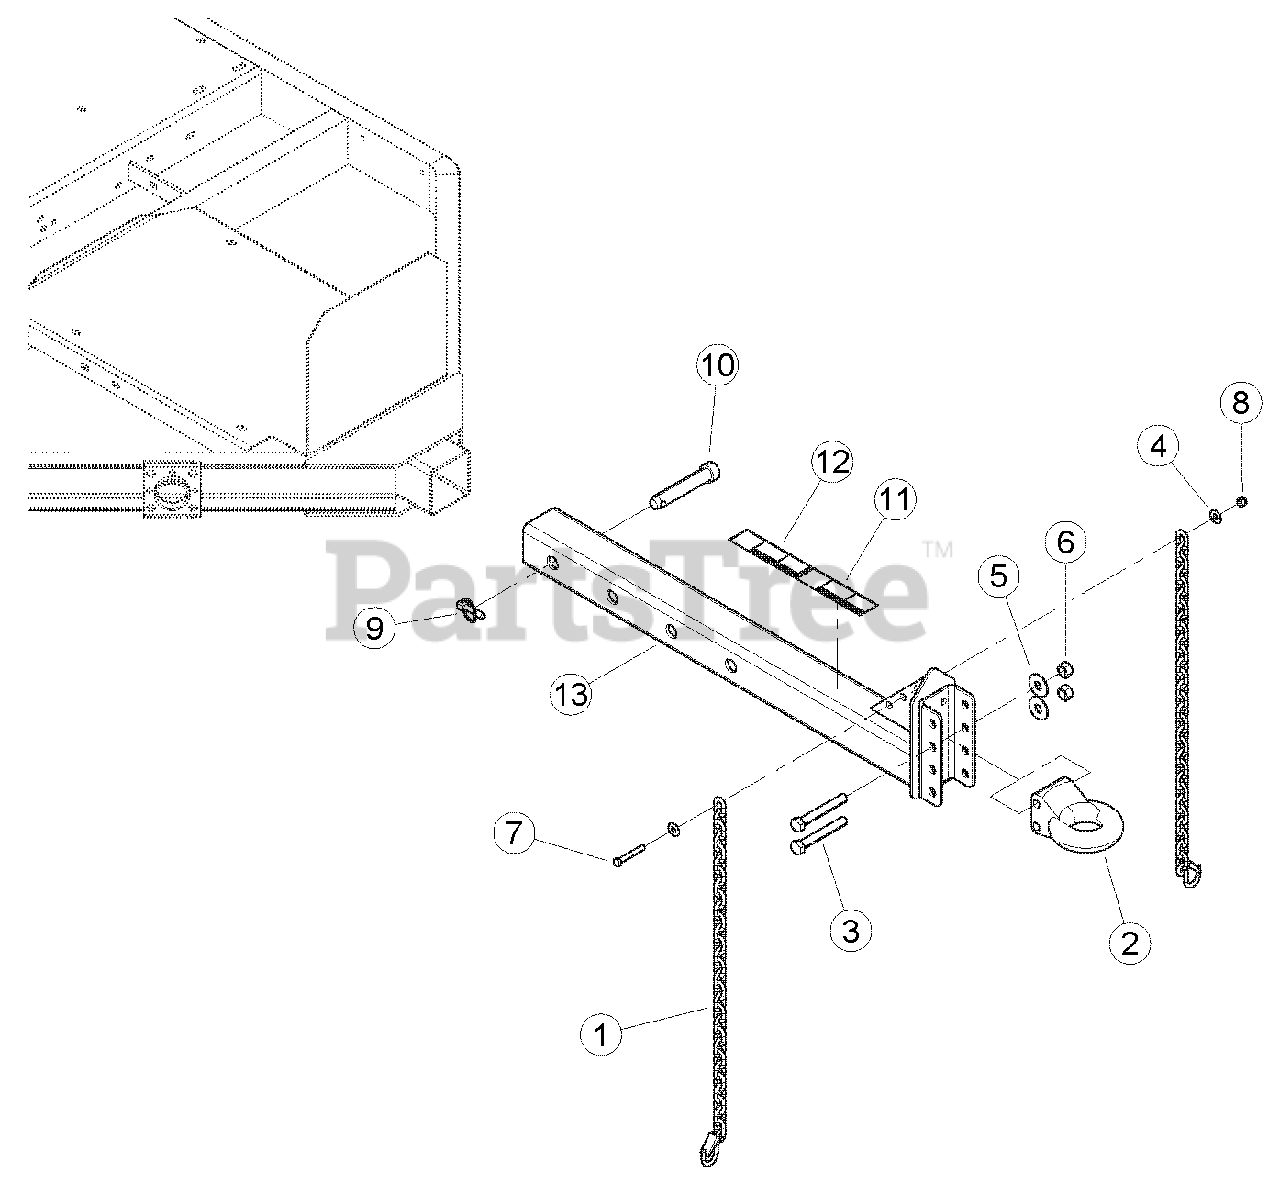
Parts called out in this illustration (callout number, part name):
1	CHAIN, SAFETY 5000 LB W/LATCH
2	HITCH, PINTLE RING, 20,000 LB
3	BOLT, 5/8 X 4-1/2 HEX GR5 ZP
4	WASHER, 3/8 FLAT ZP
5	WASHER, 5/8 FLAT ZP
6	NUT, 5/8 CENTERLOCK GR5 ZP
7	BOLT, 3/8 X 2-1/2 HEX GR5 ZP
8	NUT, 3/8 NE NYLOCK ZP
9	PIN, 7/16 X 1-3/4 LYNCH
10	TOP LINK PIN, CAT 2
11	DECAL, PINTLE SAFE COUPLING
12	DECAL, SAFE COUPLING
13	WELDMENT, HITCH POLE W/PLATE
